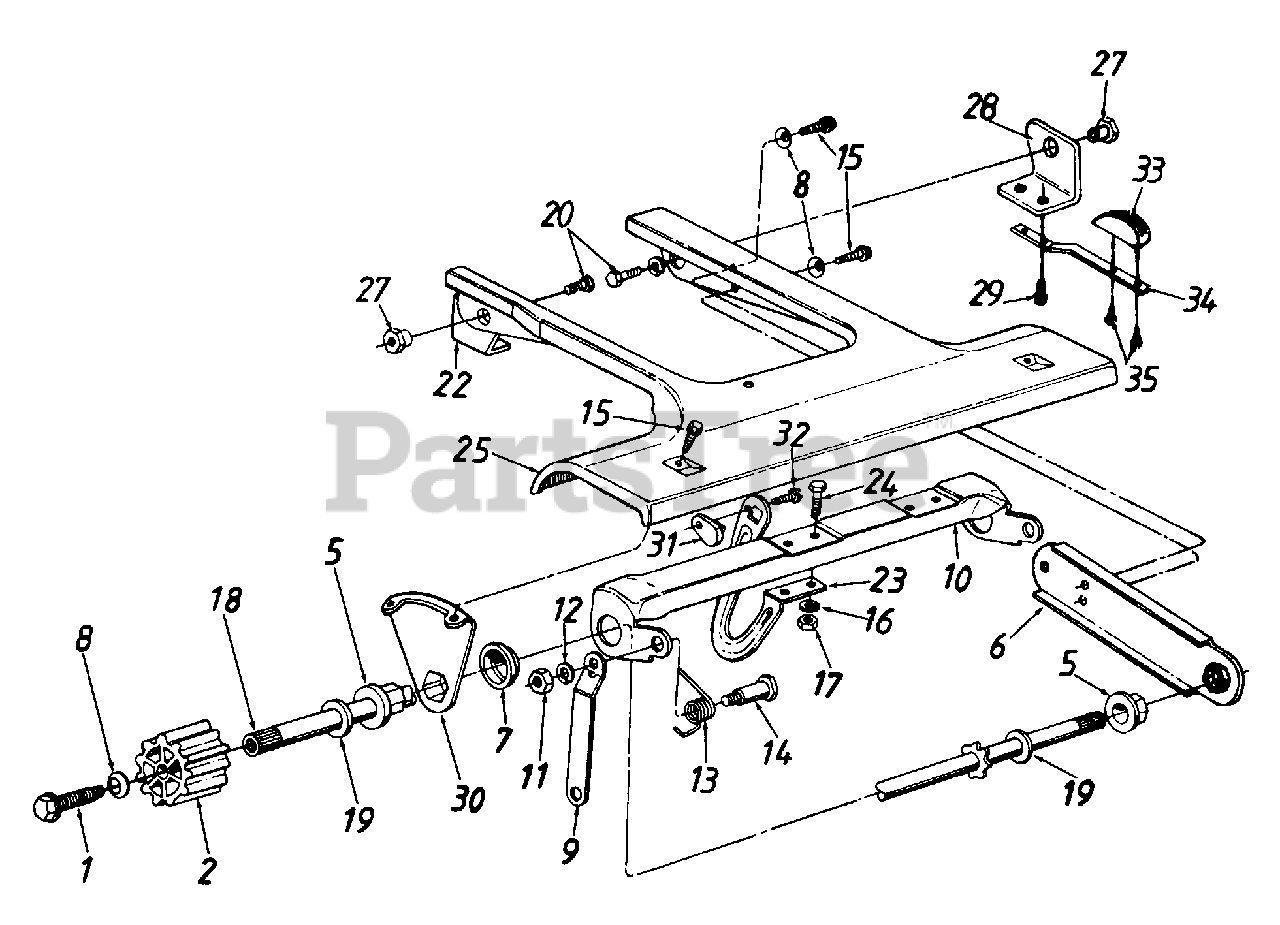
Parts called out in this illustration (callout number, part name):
1	Hex Wash. Hd. Tap Scr. 1/4-20 x .75" Lg.
2	Wheel Drive Pinion
5	Hex Flange Brg. .504" I.D.
8	Bell-Wash. .265" I.D. x .75" O.D.
11	Hex Nut 5/16-18 Thd.*
12	L-Wash. 5/16" I.D.
13	Torsion Spring-R.H.
14	Shoulder Bolt .437" Dia.
15	Hex L-Wash. Hd. AB-Tap Scr. 1/4" x .62" Lg.
16	L-Wash. 1/4" I.D.
17	Hex Nut 1/4-20 Thd.
18	Drive Shaft Ass'y.
19	Fl-Wash. .531" I.D. x .93" O.D.
20	Hex Bolt 3/8-16 x .5" Lg.*
32	Hex B-Tap Scr. #10 x .44" Lg.
33	Chain Tensioner
34	Spring
35	Hex B-Tap Scr. #10 x .38" Lg.
